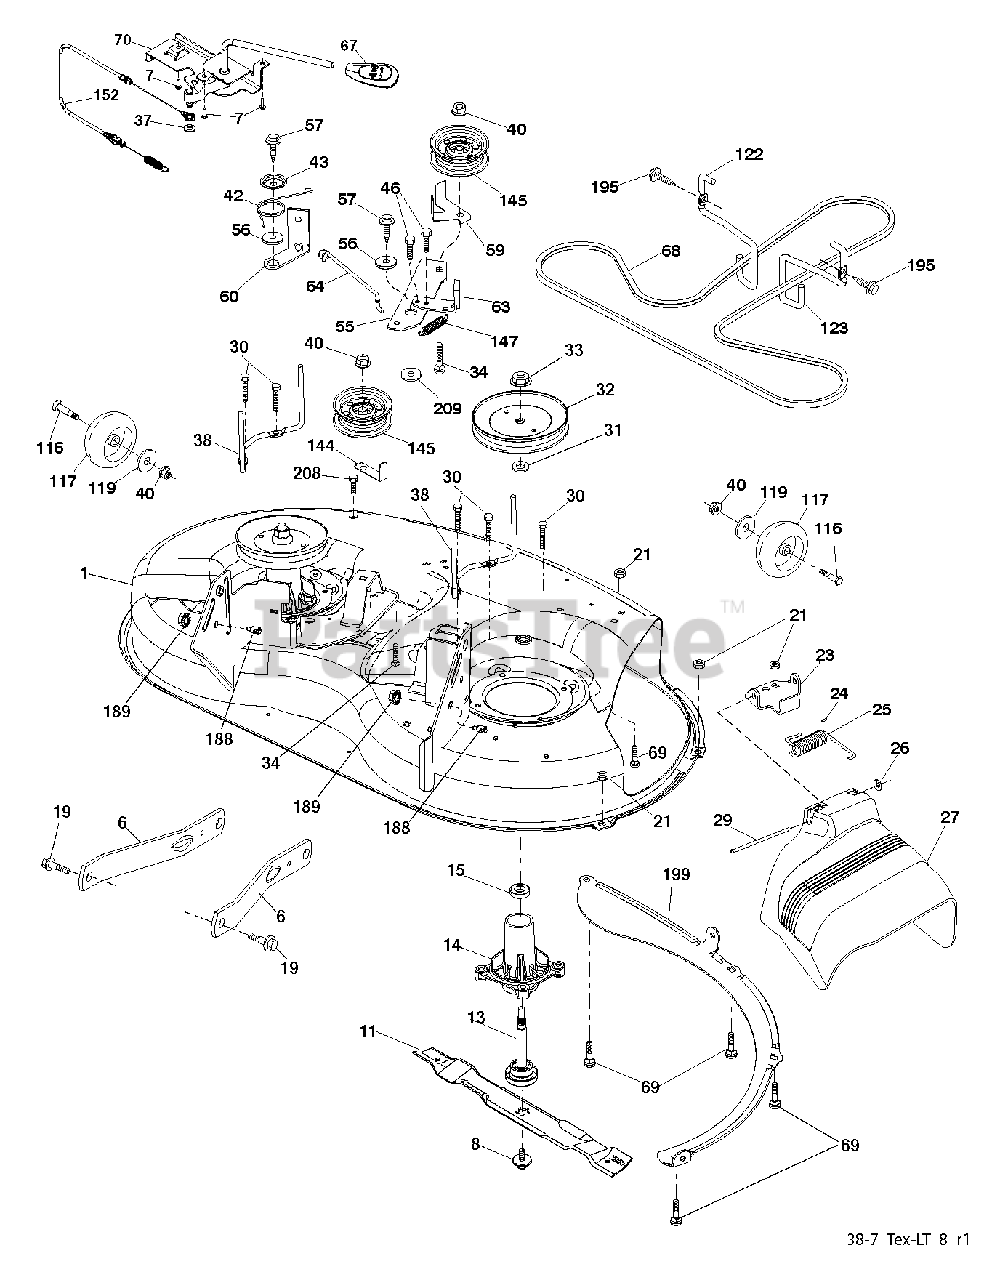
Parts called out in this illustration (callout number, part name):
1	DECK WELDMENT 38"
6	ARM.SUSPENSION.MOWER.R
7	SCREW.#10 X 0.750.BOS (2 2)
8	BOLT.WASHER.ASM.7/16-2
11	BLADE 38" PREMIUM
13	SHAFT.ASM.MDRL.N/GREASE.38
14	HOUSING.MANDREL.4PT.
19	BOLT.SHOULDER
21	LOCKNUT
23	BRKT.DEFLECTOR.38"2005+
24	CAP-SLEEVE LT
25	SPRING.TORSION.DEFLECT
26	NUT PUSH M
27	SHIELD, DEFLECTOR
29	ROD.HINGE
30	SCREW, WASHER HEAD
31	WASHER.SPACER.MANDREL
32	PULLEY.MANDREL.5.0.PD.38"
33	NUT.FLANGE.LOCK.TOP
34	BOLT.3/8-16X1.50
38	KEEPER BELT LH MANDREL
40	NUT LOCK FLG 3/8-16 UNC
42	SPRING.TORSION.BRAKE
43	SRPING.TORSION.RETAINE
46	SCREW.1/4-20X5/8
55	IDLER.ARM
56	SPACER.RETAINER
57	SCREW 3/8-16X1
59	GUARD, BELT
60	ARM BRAKE MOWER RH 38"
63	ARM BRAKE MOWER RH
64	LINK BRAKE
67	HANDLE.CLUTCH.CABLE.LT
68	Drive Belt, 38"
69	BOLT
70	CLUTCH.ASM.MANUAL.LT.TEX
116	BOLT M
117	WHEEL.GAGE.HALF.SPOKED
119	WASHER
122	KEEPER BELT ENGINE LH
123	KEEPER BELT RH
144	KEEPER BELT
145	PULLEY.IDLER.48"PRIMARY
147	SPRING RETURN
152	CABLE.CLUTCH.MANUAL.
188	STUD.FASTNER.W/ANTI-ROTATE
189	NUT LOCK HEX FLANGE 5/16-18
195	SCREW, 3/8-16X3/4
199	BAFFLE.VORTEX.FRONT.38"
208	SCREW 3/8-16X1/2
209	WASHER 12/32X2X10GA
